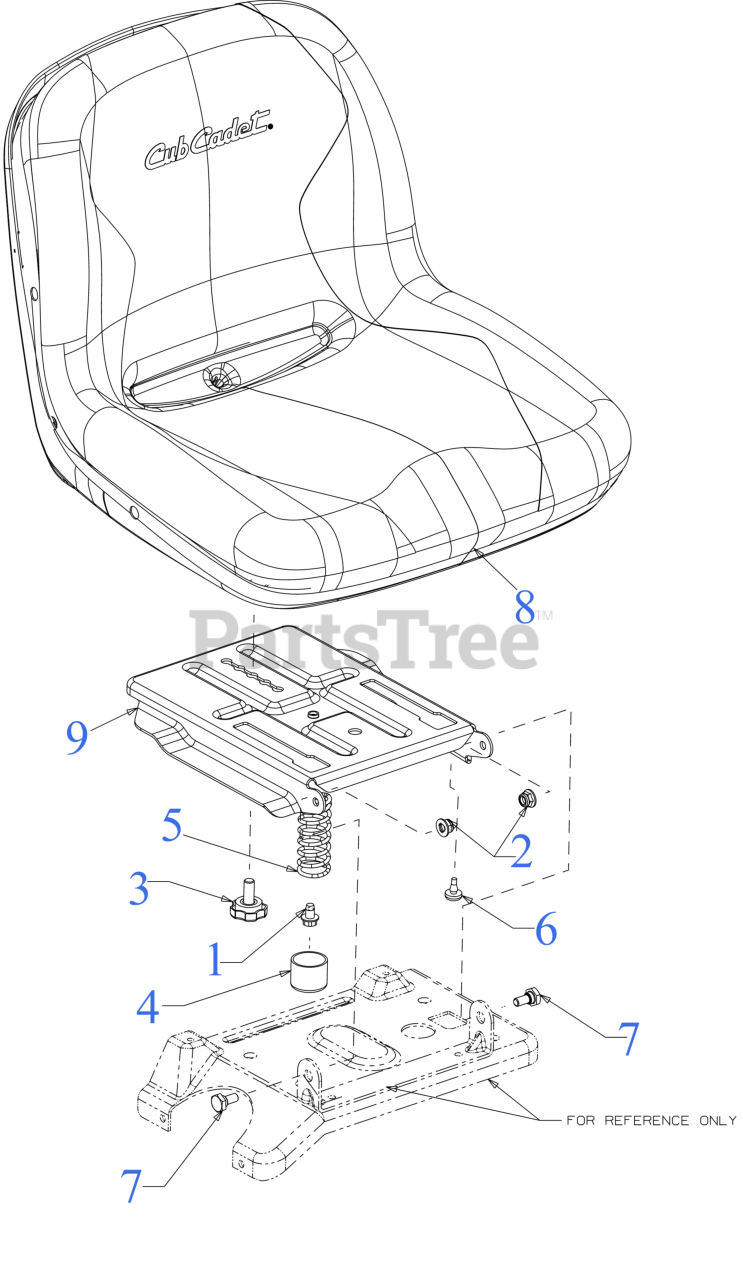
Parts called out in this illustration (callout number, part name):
1	SCREW 5/16-18 x .500
2	FLANGE LOCK NUT 5/16-18
3	SEAT ADJUSTMENT KNOB
4	SEAT SPRING CAP
5	SEAT SPRING
6	RUBBER BUMPER
7	SHOULDER SCREW .437
8	SEAT (HI/CUB/OPS & ARM/CUT/SEW)
9	MANUAL SEAT ADJUSTMENT BRACKET
